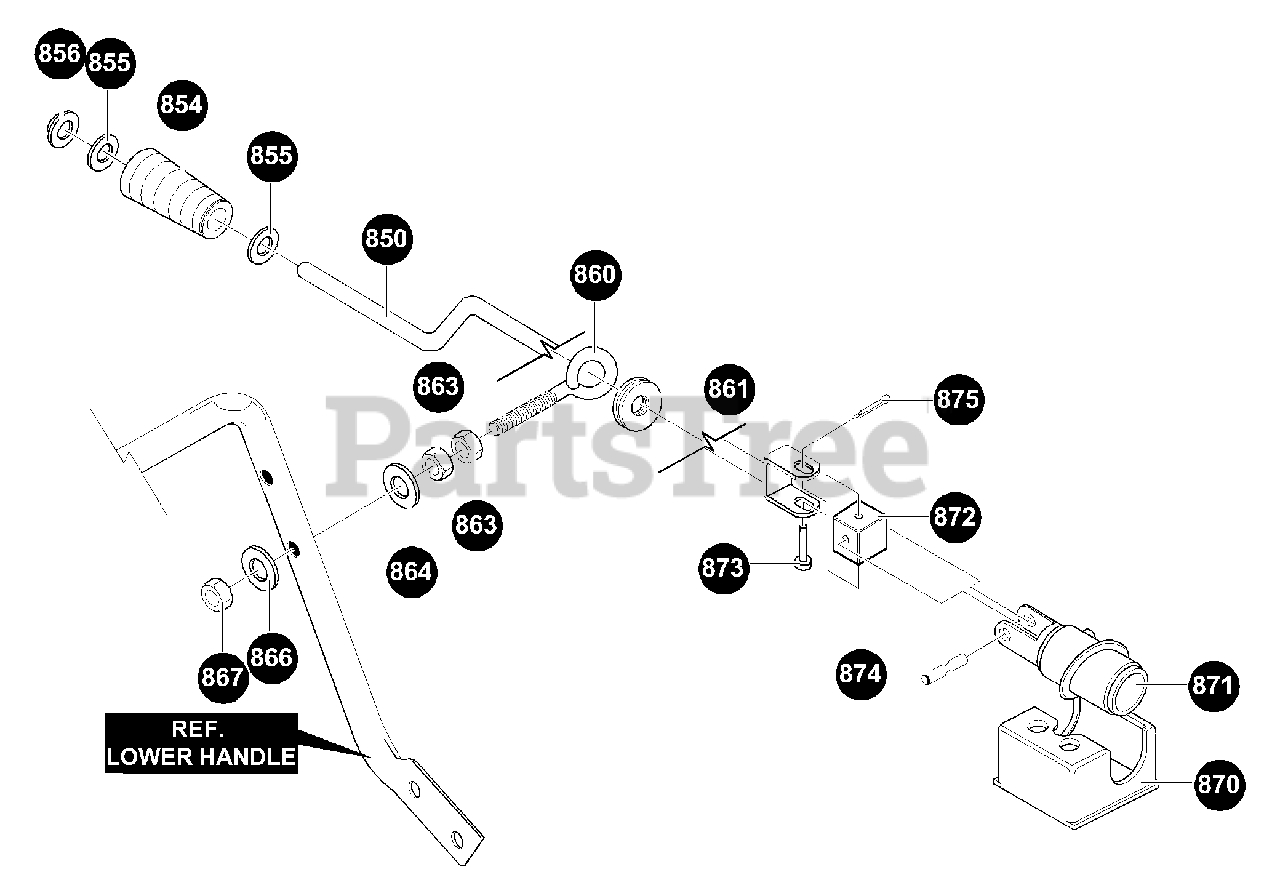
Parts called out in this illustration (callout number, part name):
850	CRANK ASSY W/YOKE
854	KNOB, SLEEVE
855	FLATWASHER .406X.81X.065
856	NUT, PUSH ON 3/8"
860	EYE BOLT, 3/8-16X6.00
861	GROMMET, EYE BOLT
863	NUT, 3/8-16 HEXJAM
864	FLATWASHER .406X.81X.065
866	FLATWASHER, .406X.81X.065
867	NUT, 3/8-16 REGHEX
870	BRACKET, WORM MOUNTING
871	WORM GEAR CHUTE ROTATE
872	BLOCK, UNIV. PIVOT
873	PIN, CLEVIS
874	PIN, UNIV. JOINT
875	COTTER PIN .06X.50
